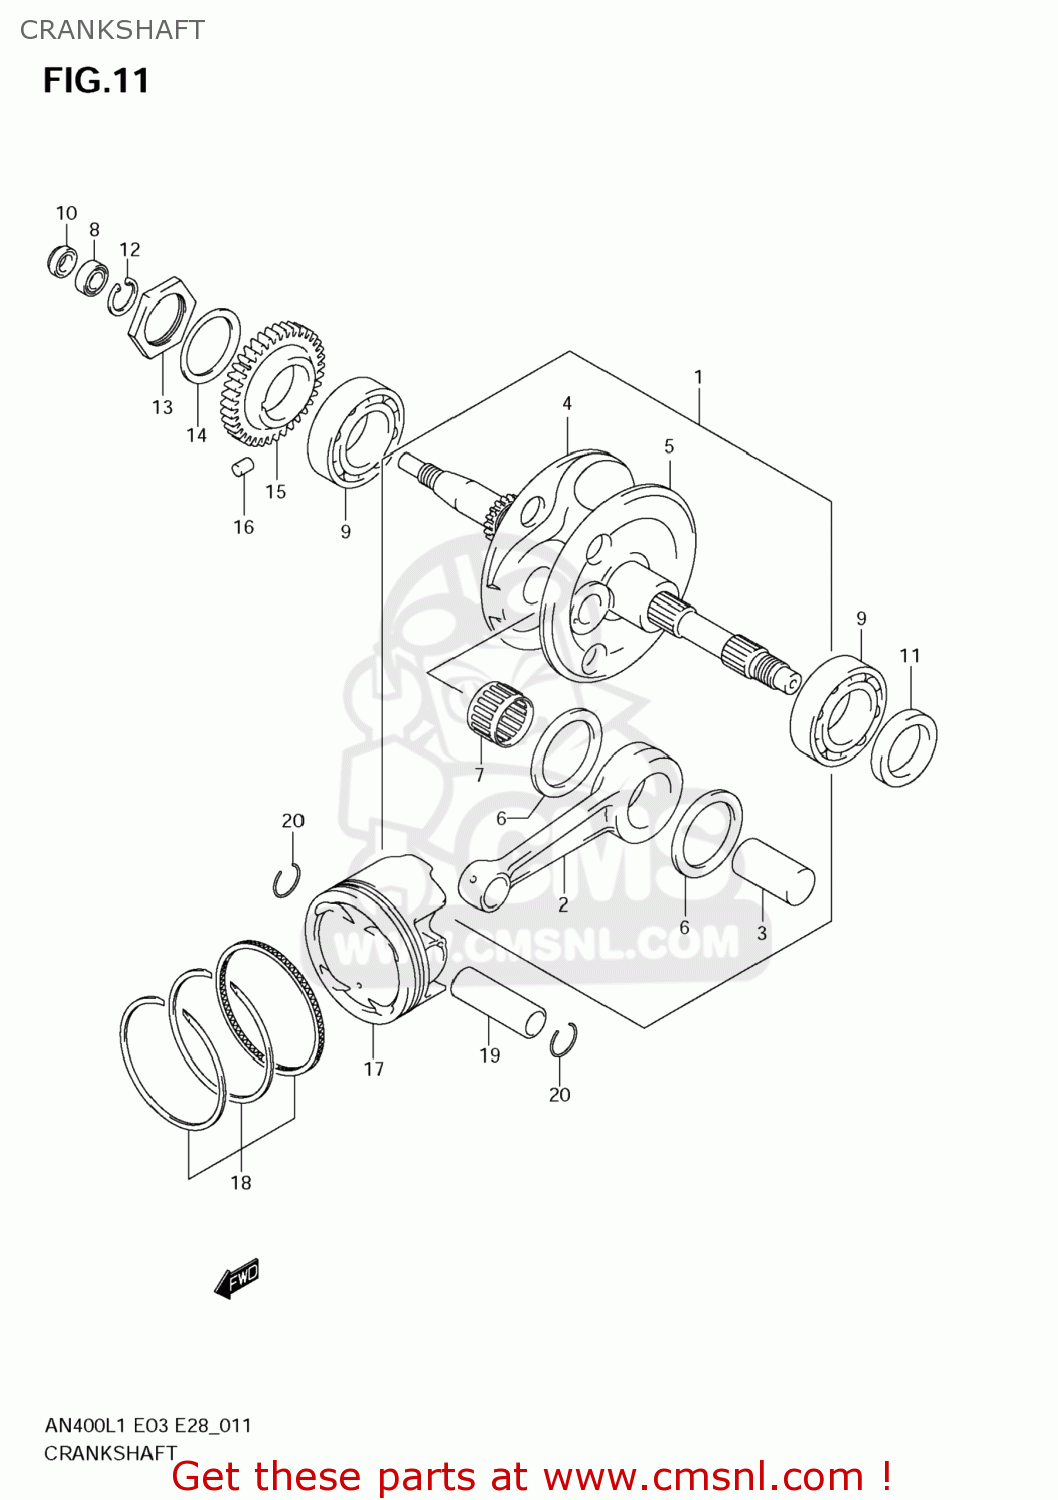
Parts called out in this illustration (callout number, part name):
1	CRANKSHAFT ASSY
2	CONNECTING ROD
3	PIN,CRANK
4	CRANKSHAFT,R
5	CRANKSHAFT,L
6	WASHER(35X55X1)
7	BEARING(35X45X22)
8	BEARING(12X32X10)
9	BEARING(35X72X17)
10	SEAL,OIL(12X29X6)
11	SEAL,OIL(34X52X6)
12	CIRCLIP
13	NUT,FLYWHEEL
14	WASHER
15	GEAR,CRANK BALANCER DRIVE
16	PIN(5X8)
17	PISTON
18	RING SET,PISTON
19	PIN,PISTON
20	CIRCLIP,PISTON PIN
